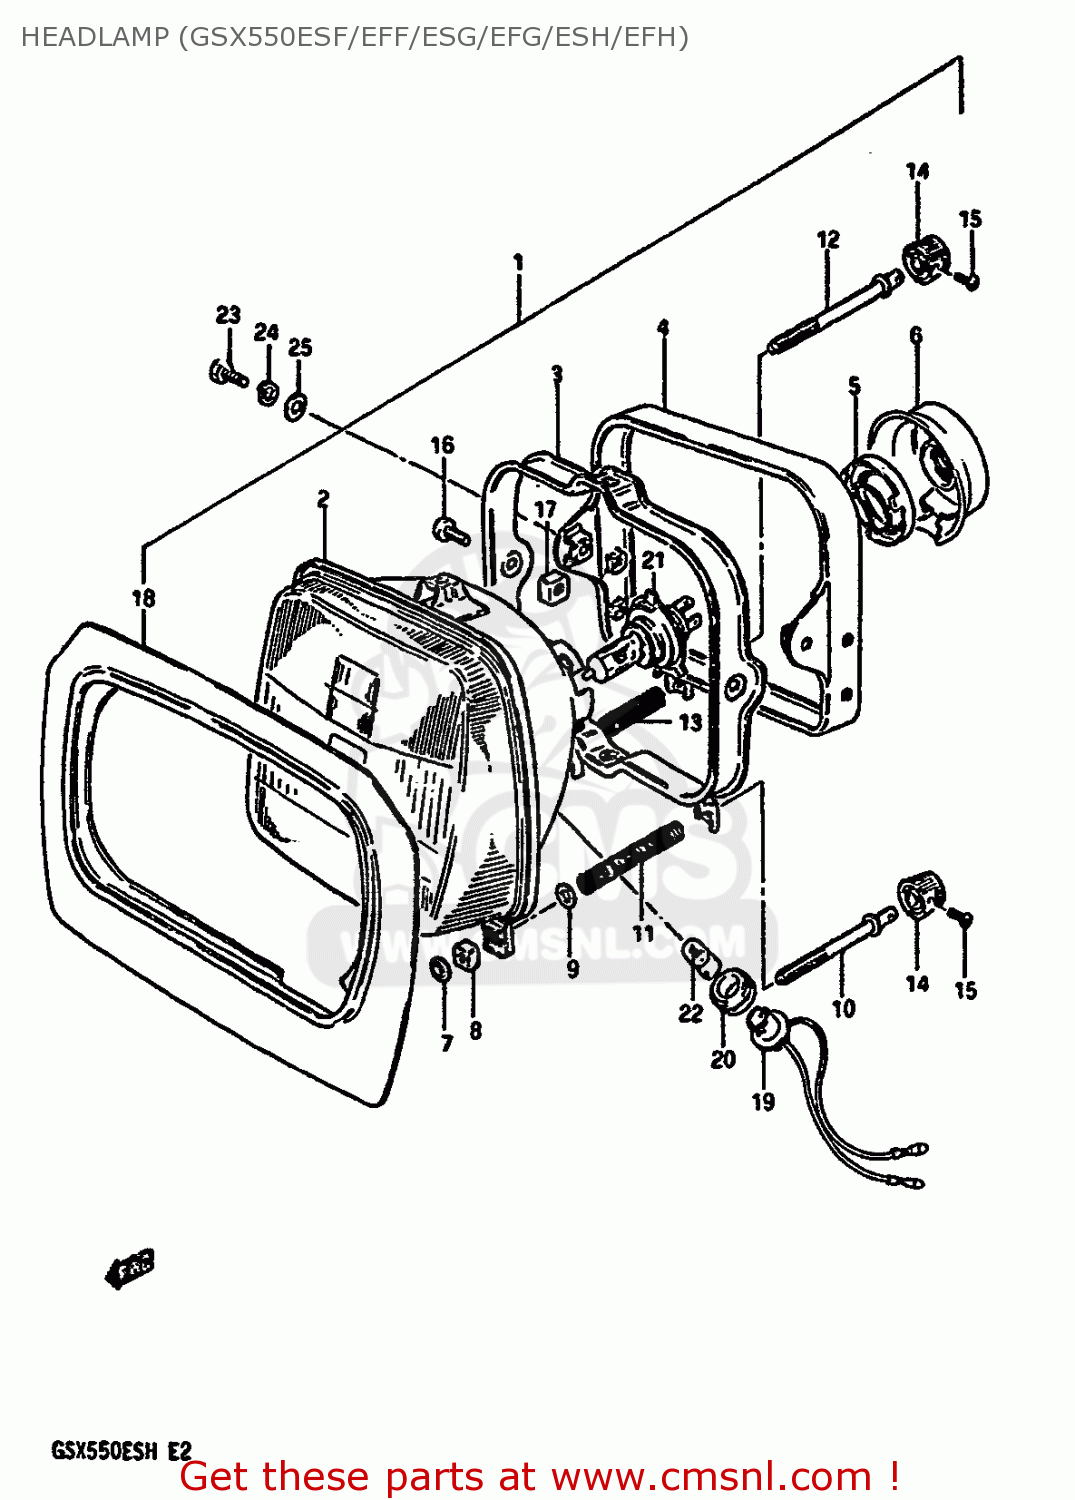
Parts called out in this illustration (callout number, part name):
1	HEADLAMP ASSY
2	UNIT
3	RING,MOUNTING
4	HOUSING,LAMP UNIT
5	HOLDER
6	COVER,HEADLAMP SOCKET
7	NUT,HEADLAMP ADJUSTER
8	NUT,HEADLAMP ADJUSTER
9	WASHER
10	SCREW,HEADLAMP ADJUST
11	SPRING
12	SCREW,ADJUSTING
13	SPRING
14	KNOB,ADJUSTER
15	SCREW
16	SCREW
17	NUT
18	SHADE
19	SOCKET
20	JOINT,RUBBER
21	BULB(12V60/55W,H4)
22	BULB(12V4W)
23	BOLT
24	WASHER,LOCK
25	WASHER, LOWER
